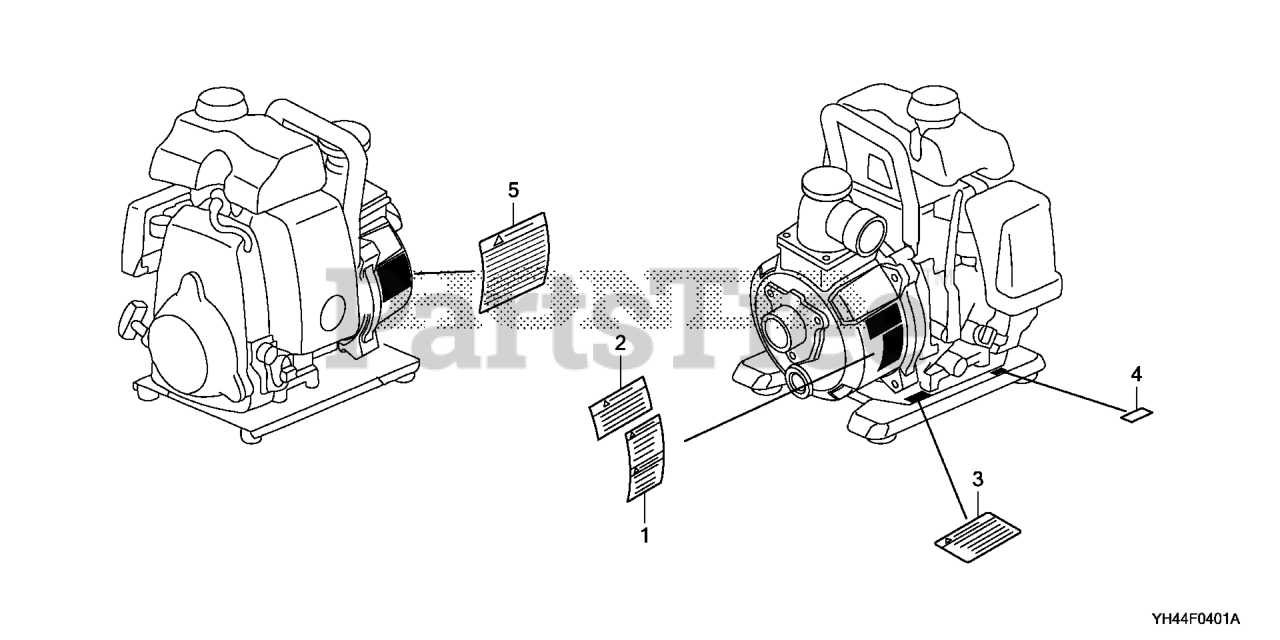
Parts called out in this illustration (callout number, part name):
1	MARK, CAUTION (PUMP)
2	LABEL, PUMP WARNING
3	MARK, OIL ALERT (ENGLISH)
4	MARK, OIL CHECK
5	LABEL, SPARK WARNING
